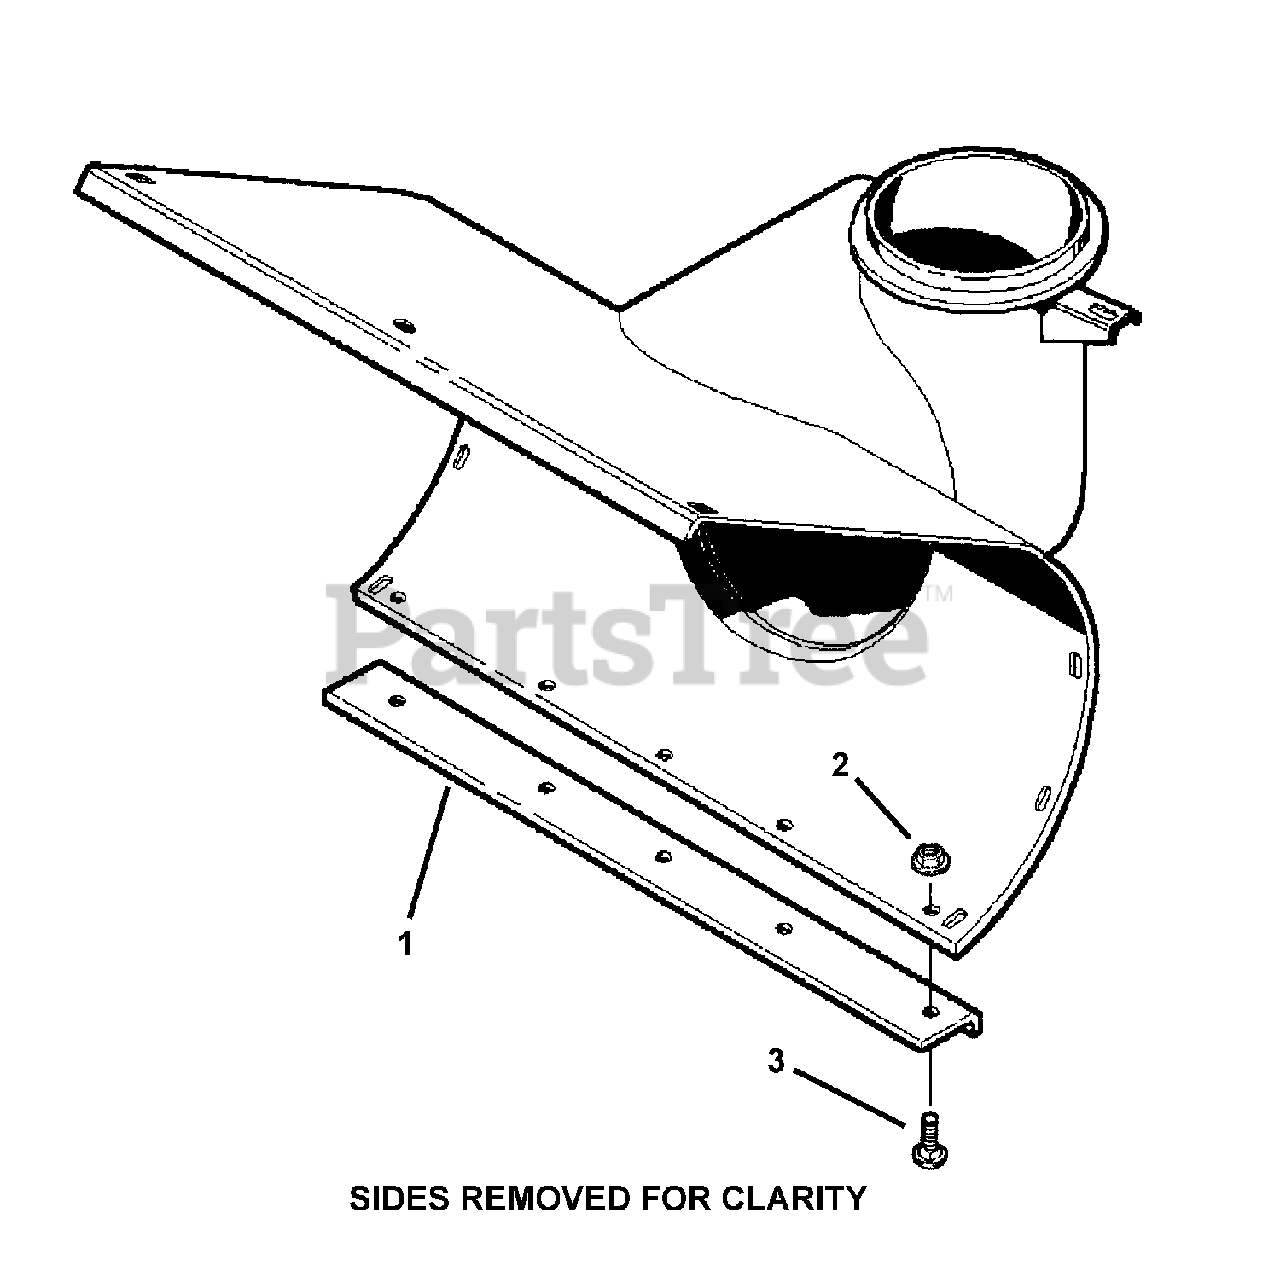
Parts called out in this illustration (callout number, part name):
1	BLADE, Scraper - 24" IST
2	NUT, Hex Flange Lock 1/4-20 YZ
3	BOLT, Short Neck Carriage 1/4-20 X 7/16 GR5 YZ
